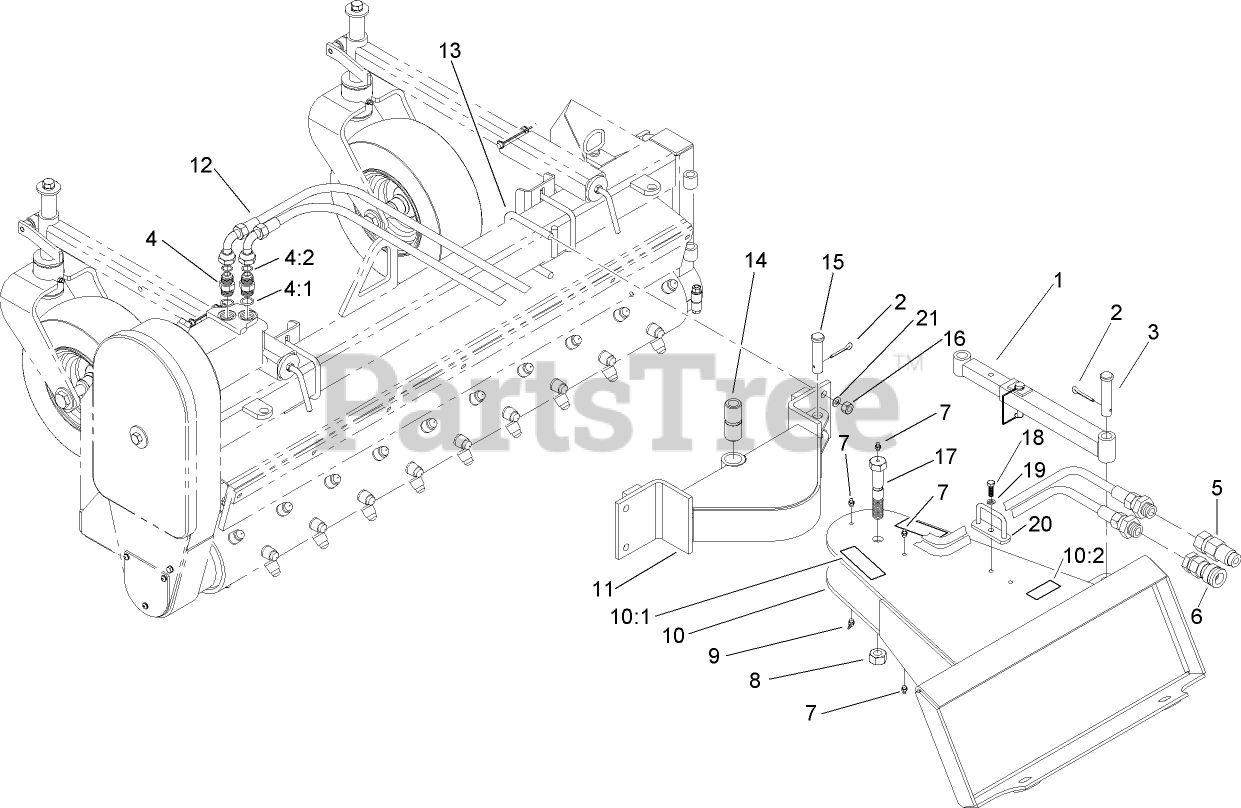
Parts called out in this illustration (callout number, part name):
1	BAR-ADJUSTMENT
2	PIN-COTTER
3	PIN-CLEVIS
4	FITTING-STRAIGHT
4:1	O-RING
4:2	O-RING
5	NIPPLE-CONNECT, PRESSURE
6	COUPLER-FACE, FLUSH
7	FITTING-GREASE
8	LOCKNUT-STOVER
9	FITTING-LUBE, 45 DEG
10	ATTACHMENT MOUNT ASM
10:1	DECAL-WARNING
10:2	DECAL-WARNING
11	MOUNT-PIVOT
12	HYD HOSE ASM
13	U-BOLT
14	BUSHING-PIVOT
15	PIN-CLEVIS
16	NUT-HH
17	BOLT-PIVOT
18	SCREW-HH
19	WASHER-LOCK
20	LOOP-HOSE
21	WASHER-LOCK
